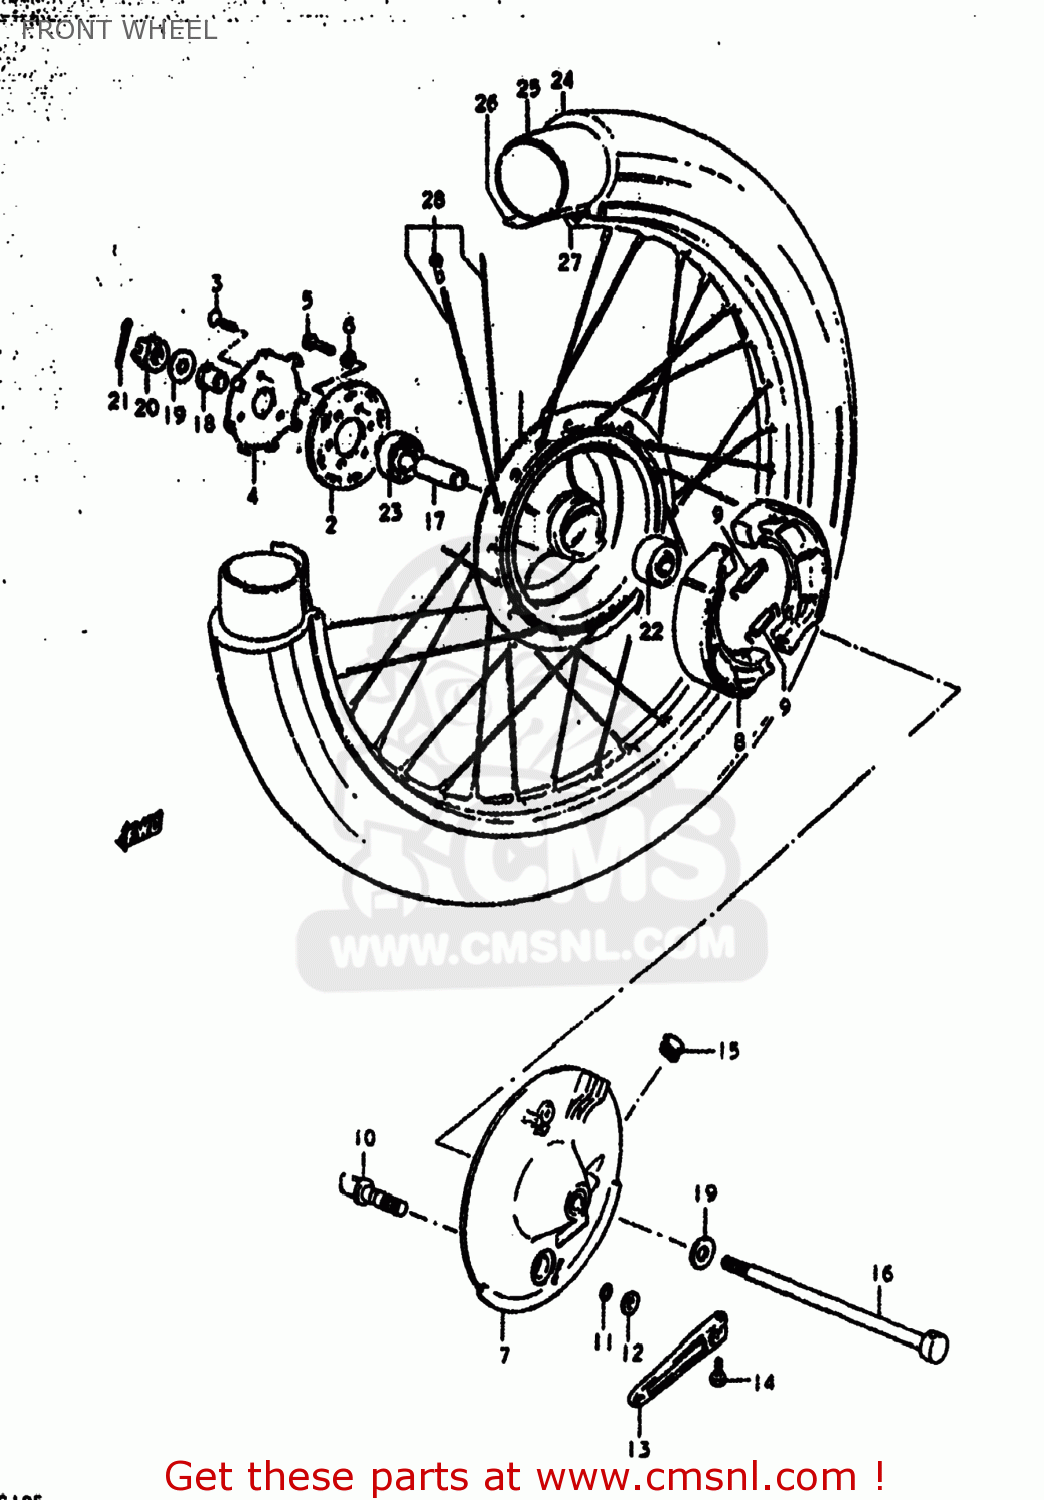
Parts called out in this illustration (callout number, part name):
1	HUB,FR WHEEL
2	FLANGE,FR HUB,R
3	SCREW
4	RETAINER,FR HUB BEARING,R
5	BOLT, UPPER
6	LOCK WASHER
7	PANEL,FRONT HUB
8	SHOE,BRAKE
9	SPRING(L:34)
10	CAM,FRONT BRAKE
11	O-RING (D:2.4 ID:13.8)
12	WASHER (14.5X22X1.6)
13	LEVER,FRONT BRAKE CAM
14	BOLT
15	CAP(OD:17)
16	AXLE,FRONT
17	SPACER (12.6X19X52)
18	SPACER,FR AXLE,R
19	WASHER
20	NUT 12MM
21	COTTER PIN
22	BEARING
23	BEARING, RH
24	TIRE,FRONT
25	TUBE
26	PROTECTOR,WHEEL,INNER
27	RIM,FR WHEEL(1.60X21)
28	SPOKE SET,FR
